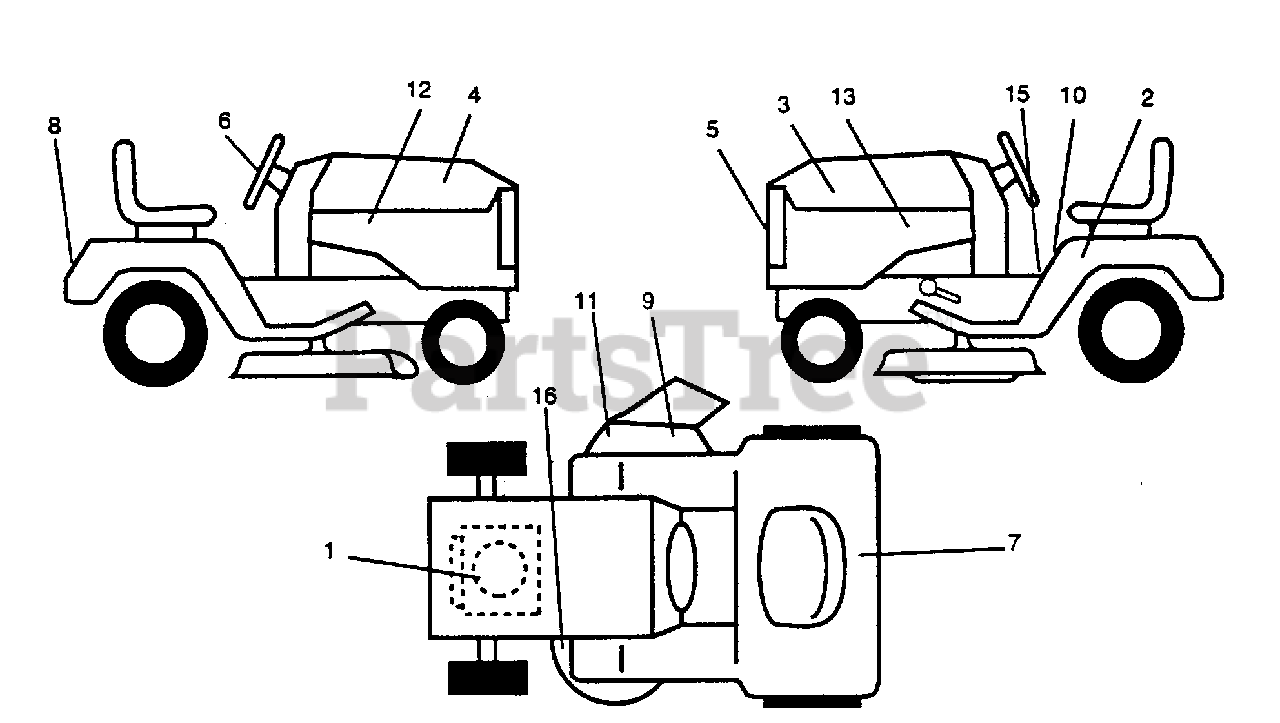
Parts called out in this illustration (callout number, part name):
1	Decal, Engine, HP
2	Decal, Indicator
3	Decal, Hood, L.H.
4	Decal, Hood, R.H.
5	Decal, Logo, Grill
6	Decal, Insert Strg. Whl.
7	Decal, Caution Battery
8	Decal, Logo, Fender
9	Decal, Deck Enviro.
10	Decal, Fender, Caution
11	Decal, Warning, Multi-Language
12	Decal, Hood, Insert, R.H.
13	Decal, Hood, Insert, L.H.
15	Decal, Instruction, Operating
16	Decal, V-Belt Schematic
